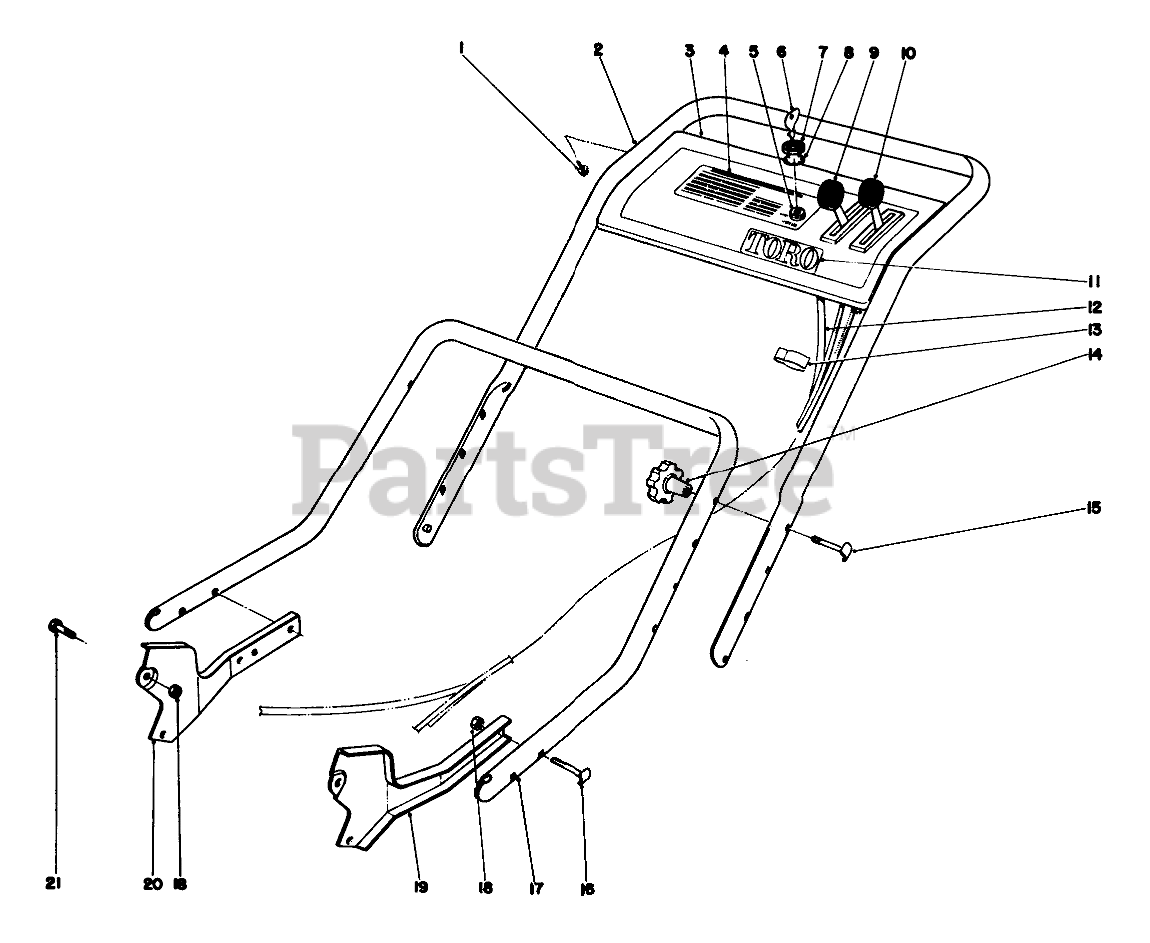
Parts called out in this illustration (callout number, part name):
1	SCREW-HWHTF
2	Upper Handle
3	Control Plate
4	Decal-Control Plate
5	Switch
6	Key
7	NUT-HH
8	WASHER-TOOTH, INTERNAL
9	SPEED CONTROL
10	Control Traction
11	TORO LOGO DECAL
12	Wire Harness
13	BOWDEN CLIP
15	HANDLE SCREW
16	Handle Screw
17	Lower Handle
18	Nut
19	Latch Handle L.H.
20	RH HANDLE LATCH
21	SCREW-HH
